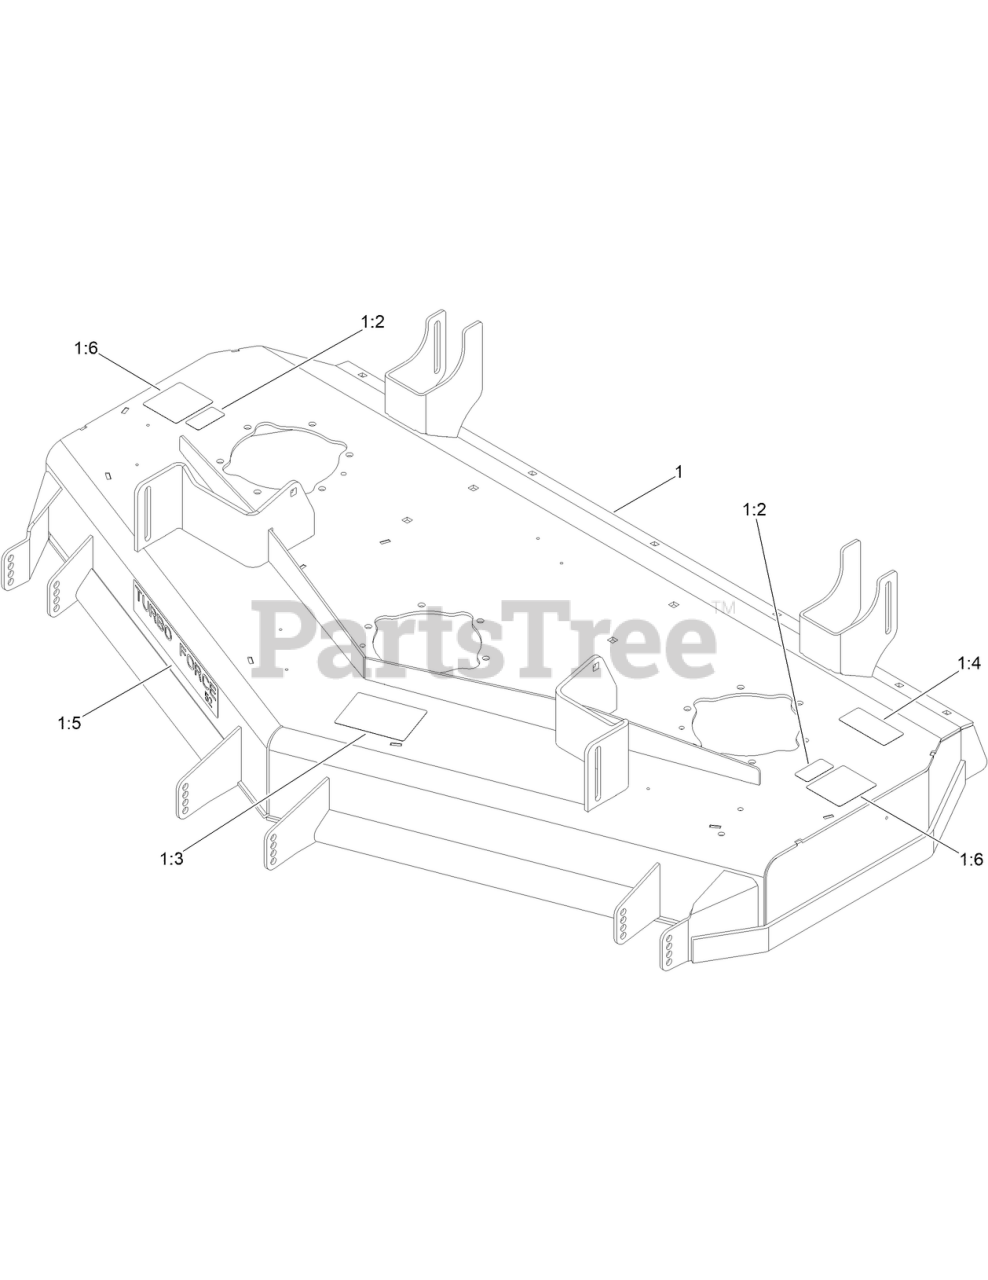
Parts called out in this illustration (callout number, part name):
1:2	DECAL-WARNING, DECK
1:3	DECAL-SCALP, ANTI
1:4	DECAL-DANGER
1:6	DECAL-NO SPRAY
